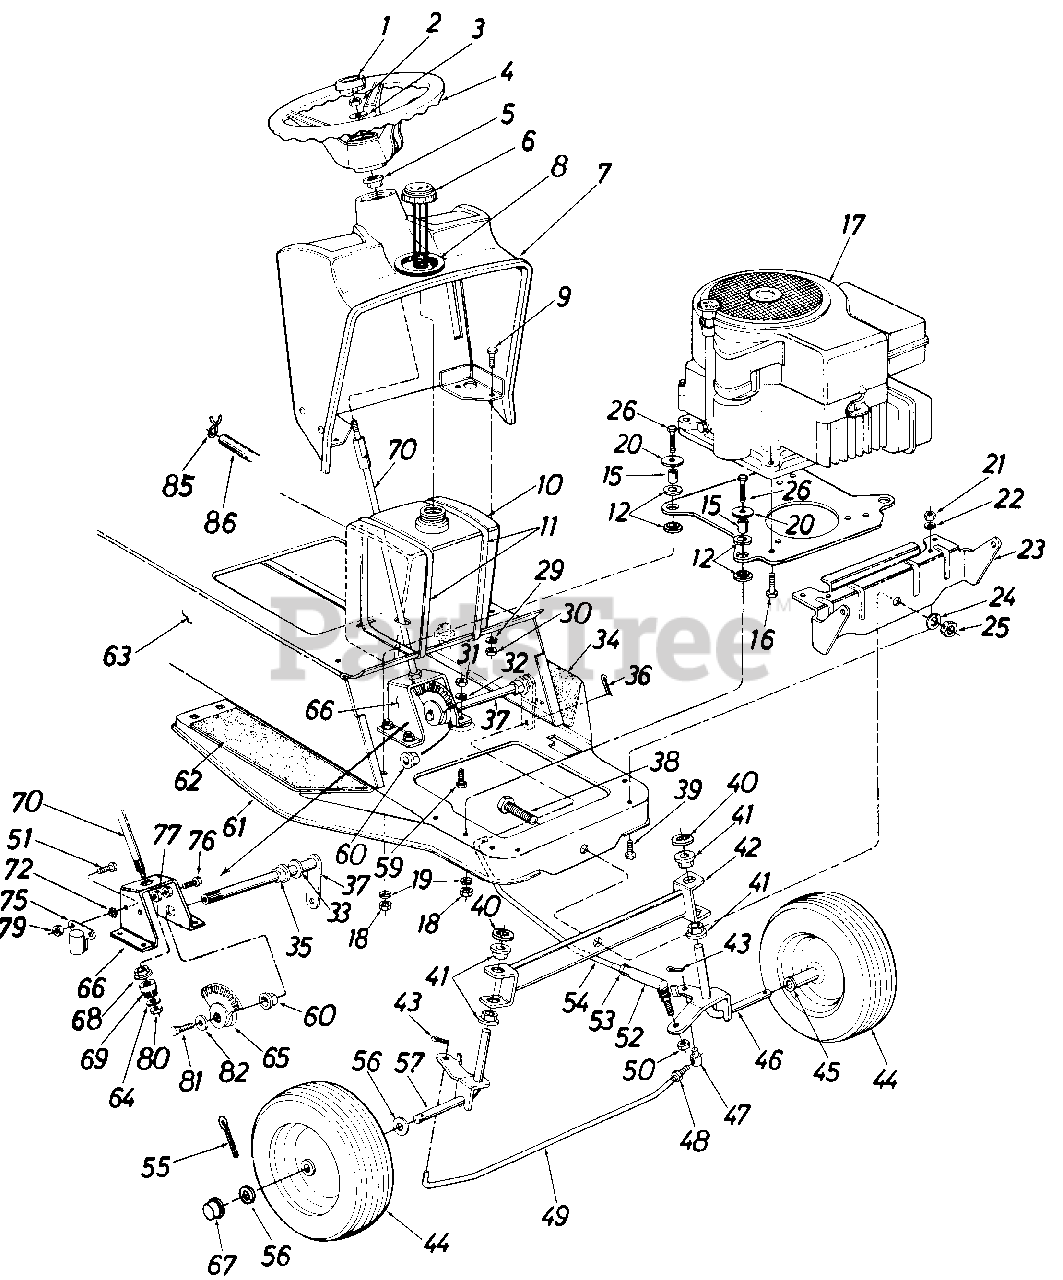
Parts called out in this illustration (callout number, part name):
1	Steering Wheel Cap
2	Hex Cent. L-Nut 5/16-18 Thd.
3	Bell-Wash. .345 I.D. x .88 O.D.
4	Steering Wheel
5	Hex Flange Bushing .63" I.D.
6	Fuel Gauge-Cap
7	Dash Panel Ass'y.
8	Rubber Grommet
9	Hex Sems Scr. 1/4-20 x .75" Lg.*
10	Fuel Tank
11	Cable Tie
12	Engine Mounting Grommet
15	Spacer
16	Hex Wash. Hd. Self-Tap Screw 3/8-16 x 1.25" Lg.
17	Engine
18	Hex Nut 5/16-24 Thd.
19	L-Wash. 5/16" Scr.*
20	Fl-Wash. .34" I.D. x 1.12" O.D. x .125
21	Hex Nut 5/16-18 Thd.
22	L-Wash. 5/16" Scr.*
23	Front Pivot Bracket
24	L-Wash. 5/8" Scr.*
25	Hex Cent. L-Nut 5/8-18 Thd.
26	Hex Scr. 5/16-24 x 1.25 H.T.
29	L-Wash. 1/4" Scr.
30	Hex Nut 1/4-20 Thd.*
31	Hex Nut 5/16-18 Thd.*
32	L-Wash. 5/16" Scr.
33	Fl-Wash. .812 I.D. x 1.38 O.D. x .100
34	Foot Pad-L.H.
35	Flange Brg. w/Flats
36	Cotter Pin 3/32" Dia. x .75" Lg.*
37	Steering Arm Ass'y.
38	Hex Scr. 5/8-18 x 1.62" Lg.
39	Hex Sems Scr. 5/16-18 x .75" Lg.
40	Push Nut
41	Hex Flange Bushing .62"
42	Pivot Bar Ass'y.
43	Cotter Pin 1/8" Dia. x .75" Lg.
44	Front Wheel Ass'y.
45	Flange Bearing
46	Front Axle Ass'y.-L.H.
47	Pivot Bushing
48	Hex Jam Nut 3/8-24 Thd.
49	Tie Rod
50	Hex Ins. L-Nut 3/8-24 Thd.
51	Hex Scr. 1/4-20 x .50" Lg.
52	Ball Joint Ass'y.
53	Hex Jam Nut 3/8-24 Thd.
54	Drag Link
55	Cotter Pin 1/8" Dia. x 1.25" Lg.*
56	Fl-Wash. .630 I.D. x 1.120 O.D. x .100
57	Front Axle Ass'y.-R.H.
59	Hex Sems Scr. 5/16-18 x .75" Lg.
60	Flange Brg. w/Flats
61	Front Frame Ass'y.
62	Foot Pad-R.H.
63	Rear Frame
64	Fl-Wash. 5/16" Scr.
65	Side Gear
66	Steering Gear Support Ass'y.
67	H u b Cap
68	Hex Flange Bushing .50" I.D.
69	Pinion Gear
70	Steering Shaft
72	Ext. L-Wash. 1/4" Scr.
75	Solenoid
76	Hex Scr. Nylon 3/8-16 x 1.25" Lg.
77	Hex Cent. L-Nut 3/8-16 Thd.
79	Hex Nut 1/4-20 Thd.*
80	Hex Cent. L-Nut 5/16-24 Thd.
81	Hex Scr. 3/8-24 x .75" Lg.
82	Bell-Wash.
85	Hose Clamps
86	Fuel Line 13" Lg.
